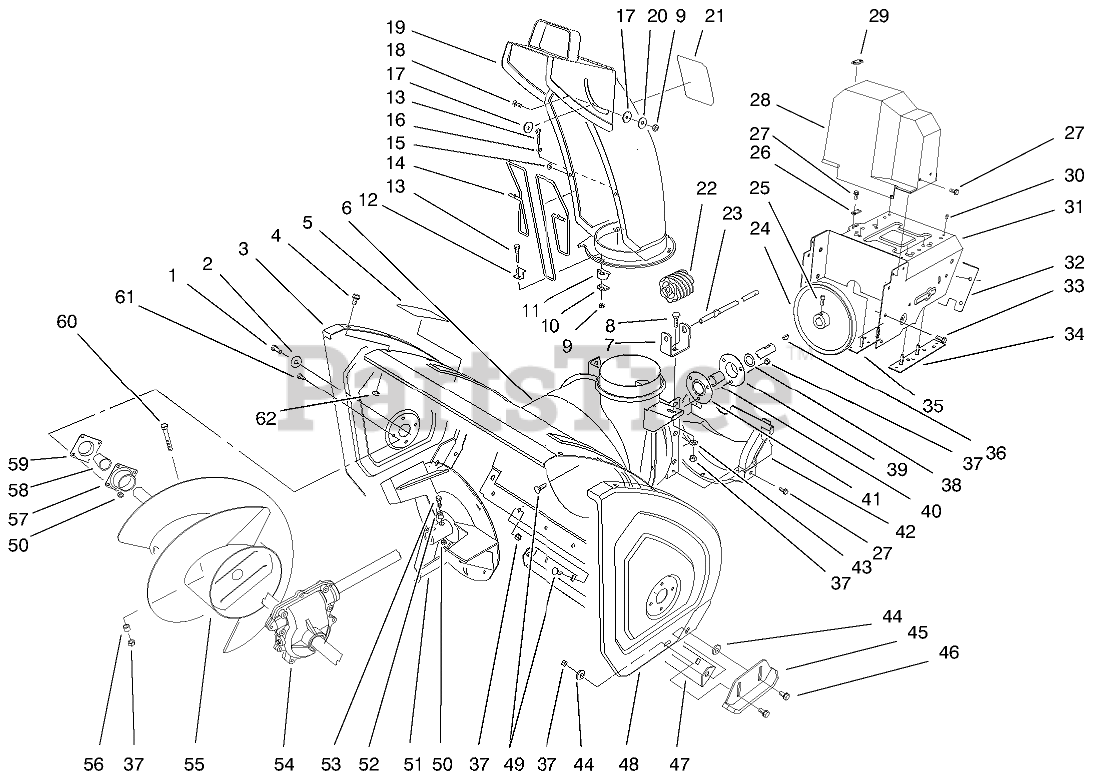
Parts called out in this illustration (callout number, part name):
1	SCREW-HH
2	WASHER
3	PLATE-SIDE, RH
4	SCREW-HHF
5	Decal-Warning, Auger (Only On: 38542)
5	Decal-Warning (Only On: 38546)
6	HOUSING ASM
7	BRACKET-WORM, CHUTE
8	BOLT-CARR
9	NUT-LOCK, NI
10	PLATE-RETAINER, CHUTE
11	RETAINER-CHUTE
12	CLIP-GUARD, CHUTE
13	SCREW-HSH
14	GUARD-CHUTE
15	NUT-PUSH
16	WASHER-FLAT
17	WASHER-PLASTIC
19	CHUTE ASM
20	WASHER-FLAT
21	Decal-Danger (Only On: 38546)
21	Decal-Danger (Only On: 38542)
22	GEAR-WORM
23	ROD-CHUTE, LOWER
24	PULLEY-IMPELLER
25	SCREW-SET, SQH
26	RETAINER-CABLE
27	SCREW-HWH
28	COVER-BELT, UPPER
29	COVER-CABLE
30	RIVET-POP
31	ENGINE FRAME ASM
32	COVER-FRAME, ENGINE
33	SCREW-HWHTF
34	LH FRAME PLATE ASM
35	RH FRAME PLATE ASM
36	KEY-WOODRUFF
37	NUT-LOCK, NI
38	WASHER-THRUST
39	FLANGE-CUP, BEARING
40	BEARING-BALL
41	FLANGE-CUP, BEARING
42	COVER-BELT, LOWER
43	WASHER-PLAIN
44	WASHER
45	SKID ASM
46	SCREW-HHF
47	SCRAPER BLADE ASM
48	PLATE-SIDE, LH
49	SCREW-CARR
50	NUT-LOCK, NI
51	BLADE IMPELLER ASM
52	SPACER
53	SCREW-HHF
54	AUGER GEARCASE ASM
55	LH AUGER ASM
55	RH AUGER ASM
56	SPACER-HUB, AUGER
57	BEARING-FLANGE, FRONT
58	BEARING
59	BEARING-FLANGE, REAR
60	SCREW-HH
61	SCREW-HH
62	NUT-LOCK, NI
